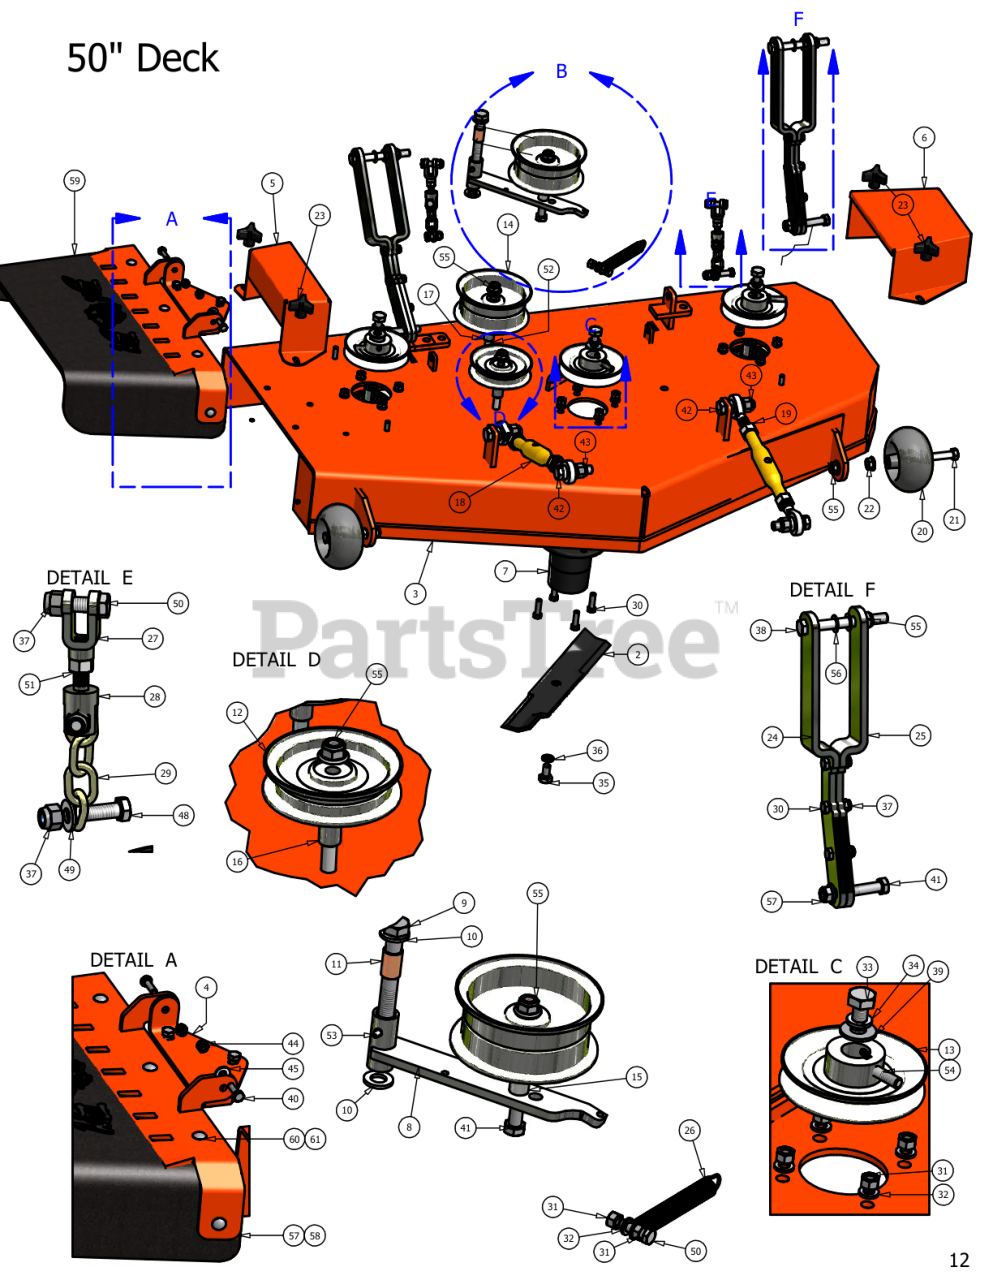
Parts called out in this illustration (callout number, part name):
1	50" Deck Belt
2	50" Fusion Blade
4	Discharge Chute Hanger
5	Spindle Cover
6	Spindle Cover
8	Deck Idler Arm
9	5/8" x 4" Hex Bolt
10	.635 ID Plastic Washer
11	5/8" ID x 1 1/8" Brass Bushing
12	4 3/4" Idler Pulley
13	5" Deck Pulley
14	5 3/4" Deck Idler Pulley
15	1 1/4" Pulley Spacer
16	Pup Pulley Spacer
17	1 3/4" Pulley Spacer
18	Turnbuckle
19	3/4" Left Handed Nut
20	Anti-Scalp Rollers
21	1/2" x 4" Bolt (Grade 8)
22	1/2" Flange Nut
23	5/16" Knob
24	Deck Support Arm (left)
25	Deck Support Arm (Right)
26	Deck Idler Spring
27	Female Yoke
30	3/8" x 1 1/4" Hex Bolt
31	3/8" Hex Nut
32	3/8" Lock Washer
33	1/2" x 1 1/2" Bolt Fine Threaded
34	1/2" Lock Washer
35	5/8" x 1.5" Fine Threaded Bolt
36	5/8" Lock Washer
38	1/2" x 4 1/2" Bolt
39	1/2" Cup Washer
40	5/16" x 1" Hex Bolt
41	1/2" x 2 1/2" Hex Bolt
42	5/8" x 2 1/2" Hex Bolt
43	5/8 Std NC Nylock Nut
44	5/16" Nylock Nut
45	.360 ID Plastic Washer
46	3/8" x 3/4" Hex Bolt
47	3/8" Flange Nut
48	3/8" x 1" Hex Bolt
49	3/8" Flat Washer
50	3/8" x 1 1/2" Hex Bolt
51	3/8" Fine Threaded Jam Nut
52	1/2" x 3 1/2" Bolt
53	Grease Fitting (Drive-In Type)
54	3/8" Hex Bolt
55	1/2" Flange Lock Nut
56	1/2" Brass Washer
57	2007 Hanger Plate
58	2007 Lower Hanger Plate
59	Rubber Side Discharge
60	5/16" x 1 1/2" Carriage Bolt
61	5/16" Nylock Flange Nut
